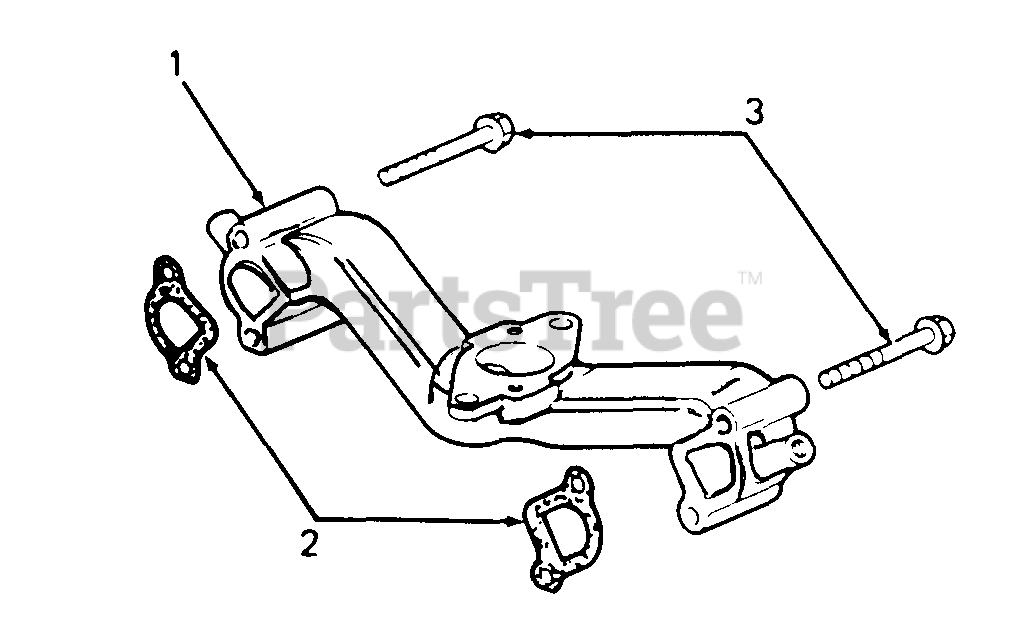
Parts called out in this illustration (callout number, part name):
1	Manifold Assy
2	Gasket, Intake Manifold
3	Screw, Sems
